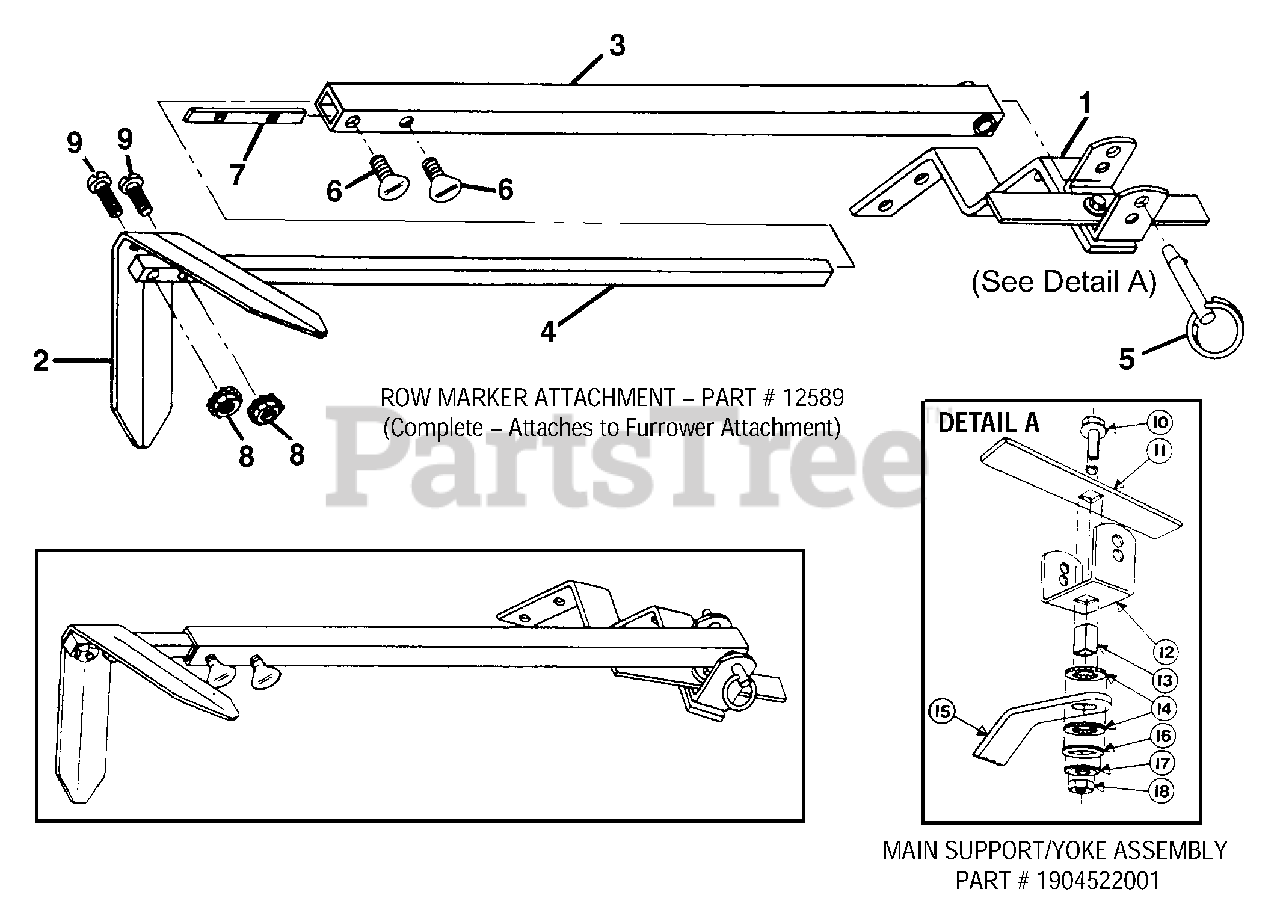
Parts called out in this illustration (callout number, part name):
1	Main Support & Yoke Assy-complete.
2	Marker Blade-blade only
3	Marker Arm-main arm
4	Marker Arm-extension arm with stop pin
5	Hitch Pin-
6	Thumbscrew-1/4-20 x 1/2, not avail. sep.
7	Nut Bar-
8	Nut-hex, 10-24 w/attached start washers, not avail. sep.
9	Screw-round hd.,10-24 x 1, not avail. sep.
10	Screw-hex flanged locking, 3/8-16 x 1-1/2
11	Stop Bar
12	Yoke
13	Tube Key-square
14	Washer-friction
15	Main Support
16	Washer-square hole
17	Washer-disc spring
18	Nut-hex 3/8-16
12589	Row Marker Attachment
1904522001	Row Marker Main Support & Yoke Assembly
